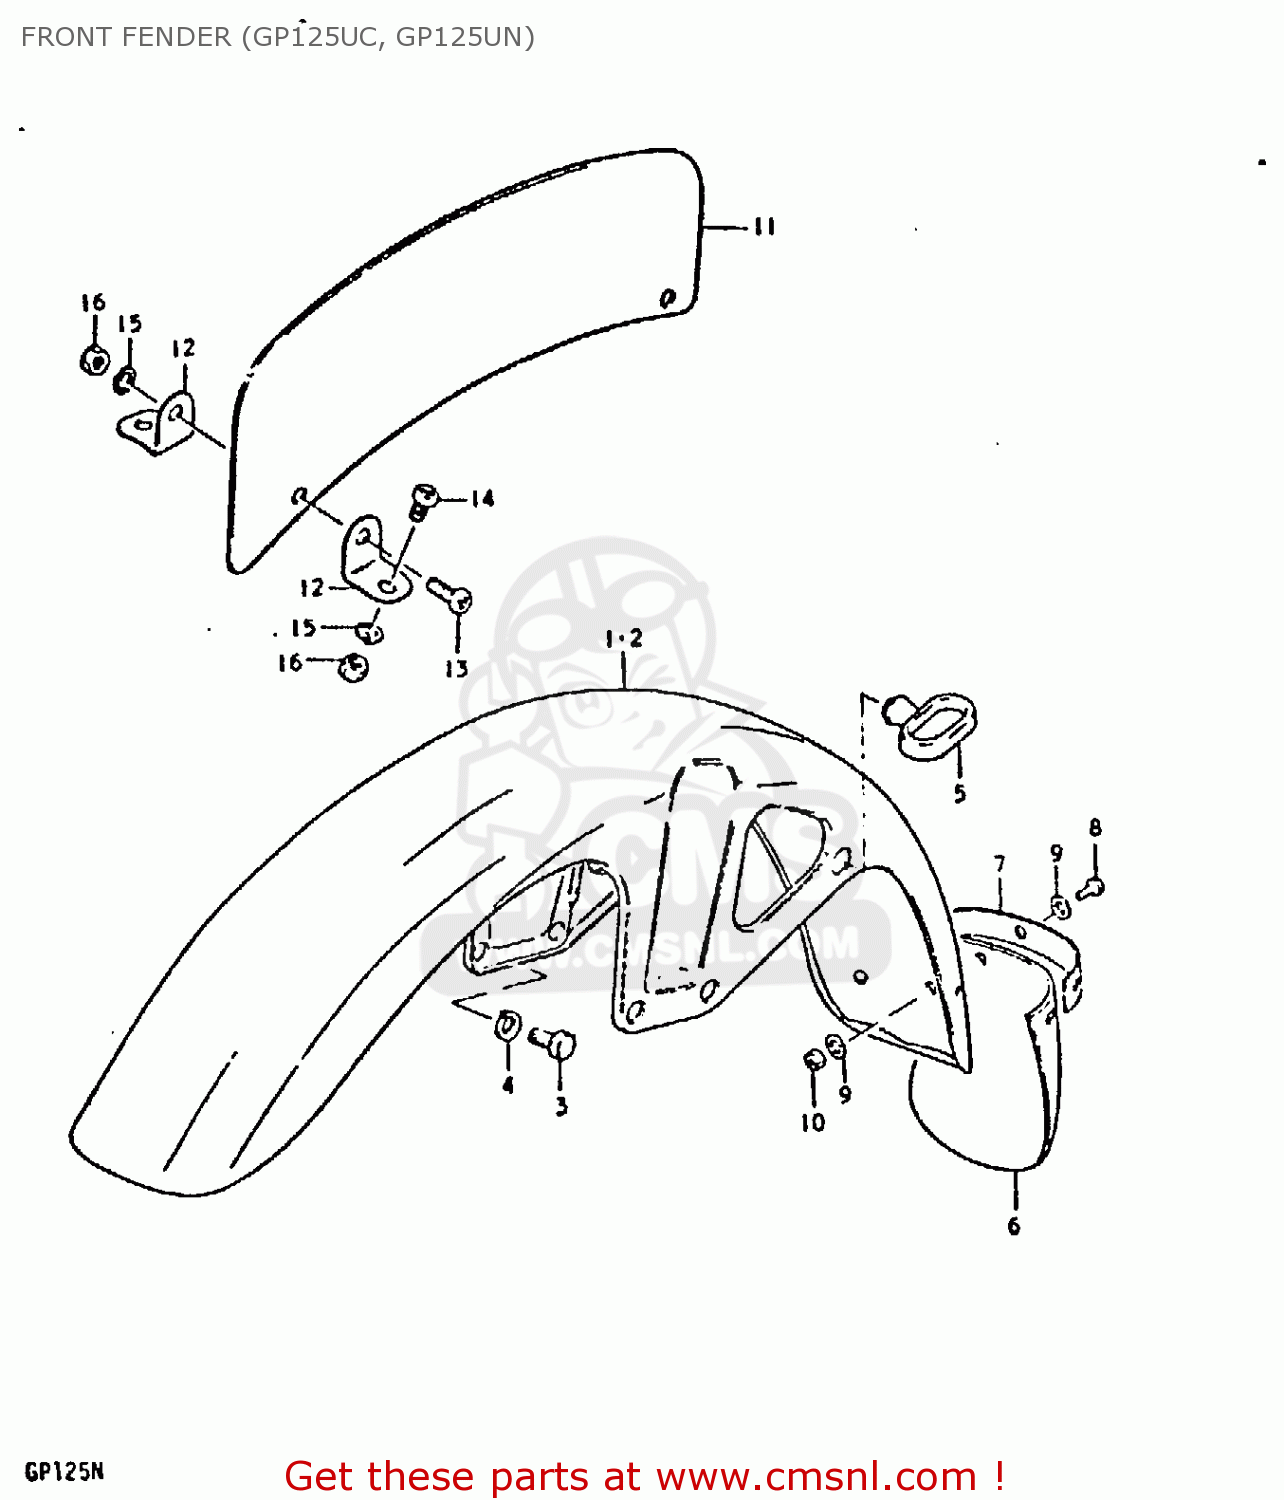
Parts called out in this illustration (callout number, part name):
2	FENDER, FRONT
3	BOLT
4	LOCK WASHER
5	GUIDE,CABLE
6	FLAP,MUD
7	PLATE,MUDFLAP
8	SCREW 4X10
9	WASHER
10	NUT 4MM
